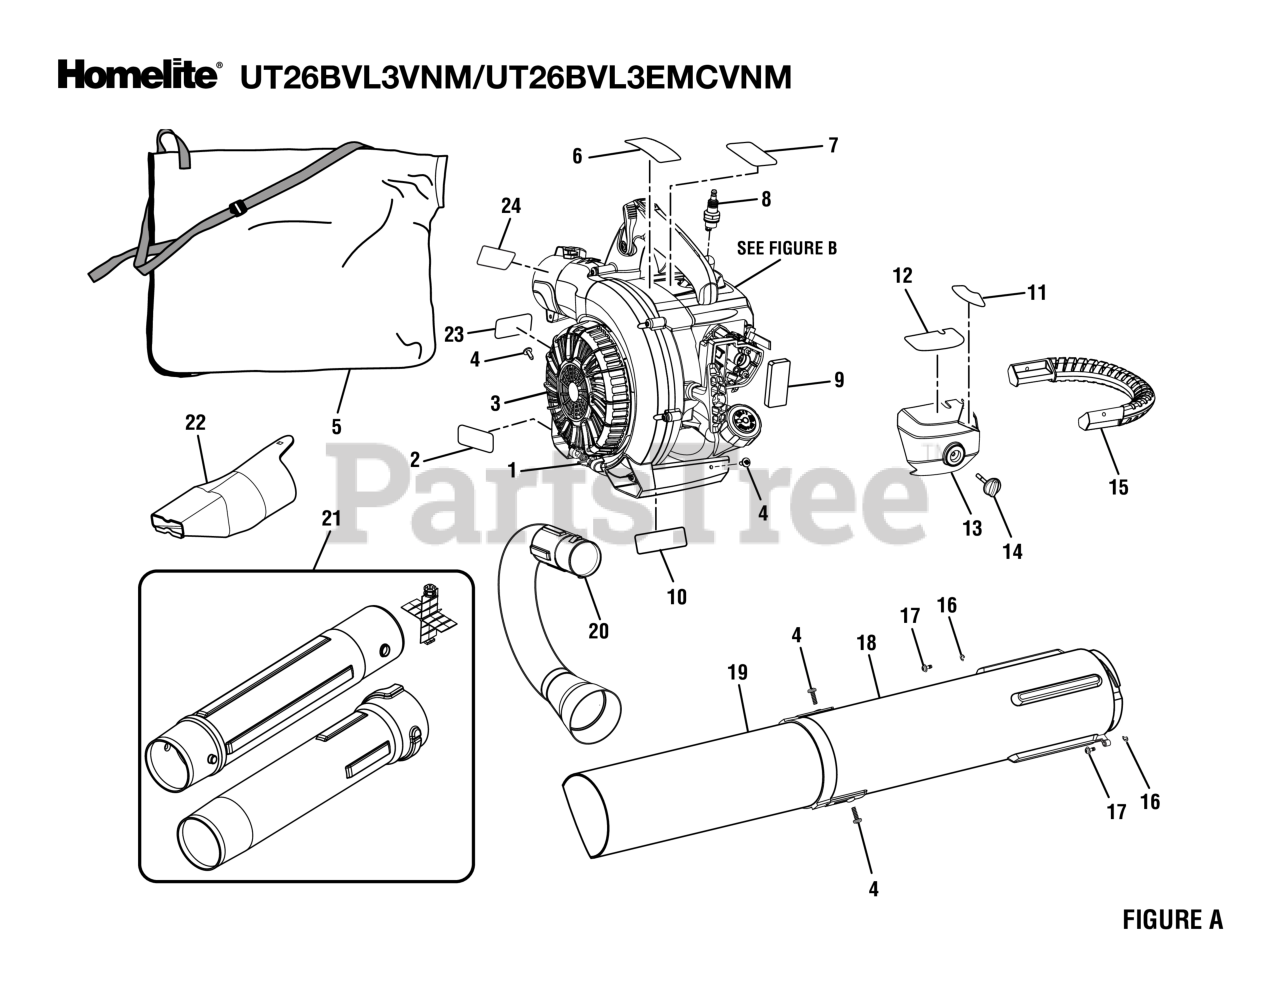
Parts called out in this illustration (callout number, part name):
1	Vacuum Door Spring
2	Warning Label (Combustion)
3	Vacuum Door
4	Vacuum Tube Screw (10-14 x 1/2 in., T25 Torx Truss Hd. T.F.)
5	Vacuum Bag w/Shoulder Strap
6	Warning Icon Label
7	Logo Label (Small)
8	Spark Plug (Champion RCJ6Y)
10	EMC ICES-2/NMB-2 Label (Canada)
11	Choke Label
12	Starting Label
13	Air Filter Cover
15	Vacuum Handle
16	E-ring (Retaining Ring)
17	Screw (1/4-20 x 3/4 in., Soc. Hd.)
18	Upper Vacuum Tube
19	Lower Vacuum Tube
20	Vacuum Bag Adaptor
21	Blower Tube Assembly
22	Wet Leaf Nozzle
23	Hot Surface Label
24	Tube Removal Label
